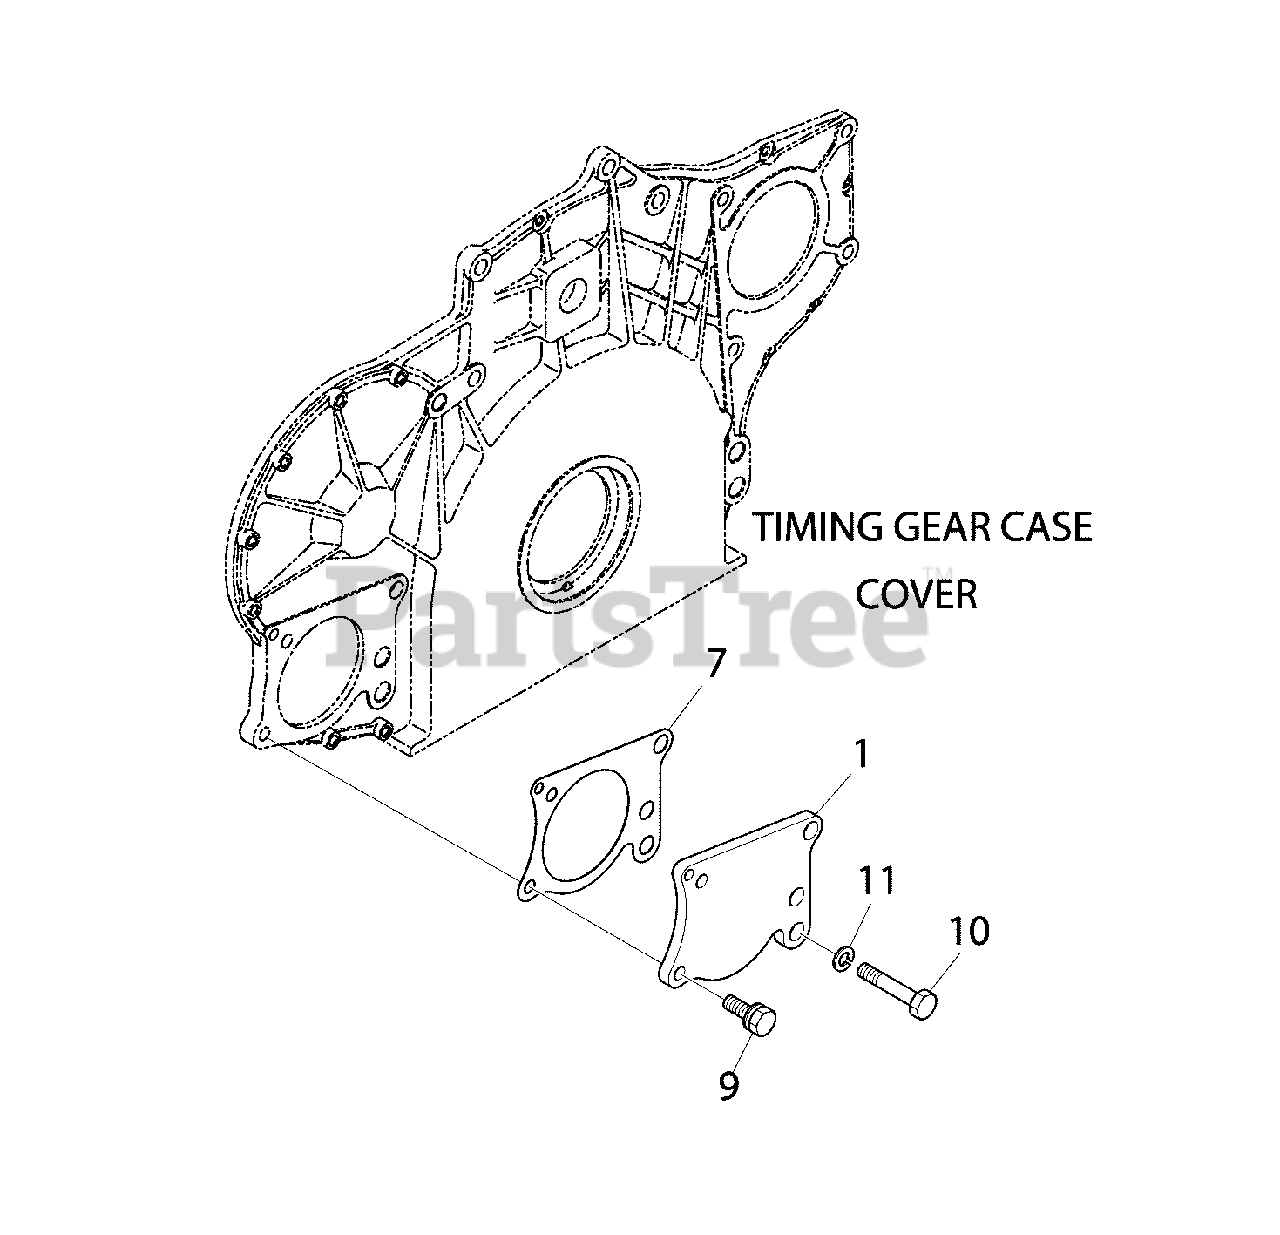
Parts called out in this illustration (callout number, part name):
1	* COVER
7	GASKET, POWER STEERING
9	* BOLT
10	* BOLT, HEX
11	* WASHER, SPRING
